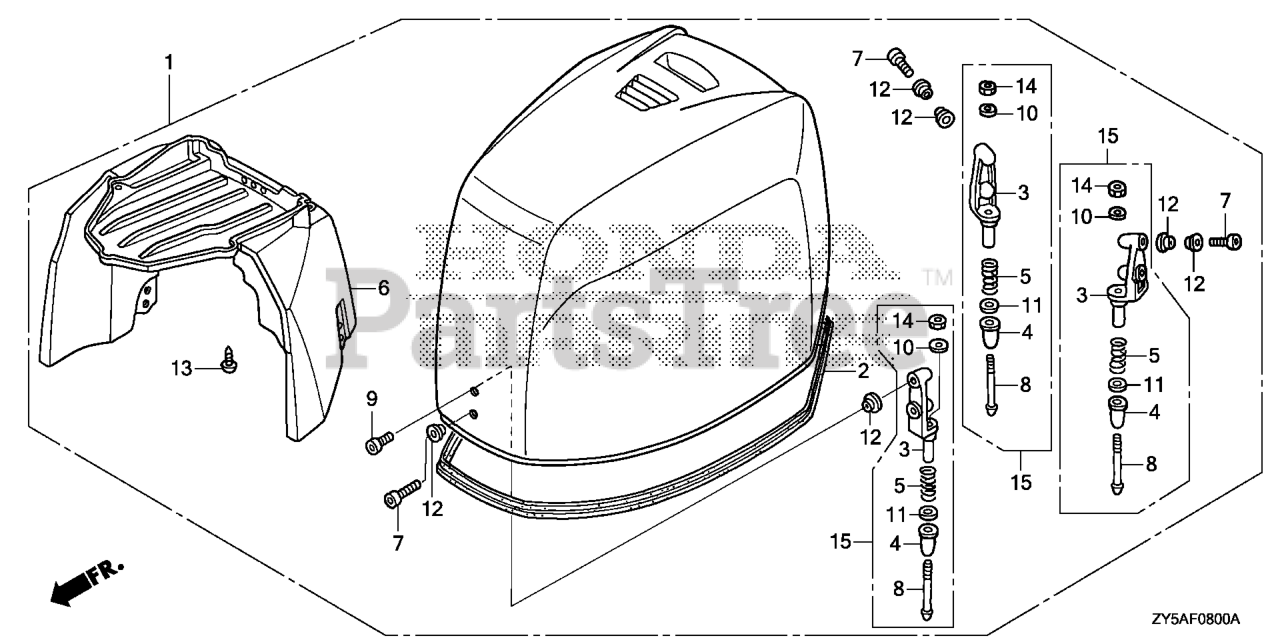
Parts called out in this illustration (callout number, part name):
1	COVER ASSY., ENGINE *NHB14M* (AQUA MARINE SILVER METALLIC)
1	COVER ASSY*NH565*
2	SEAL, ENGINE COVER
3	BRACKET, HOOK
4	DAMPER, HOOK
5	SPRING, LOCK ADJUSTER
6	GUIDE, ENGINE COVER AIR
7	BOLT, SOCKET (6X20)
8	BOLT, COVER LOCK
9	BOLT, SOCKET (6X16)
10	WASHER, PLAIN (6MM) Use from Frame SN 4800713.
11	WASHER, PLAIN (12MM)
12	COLLAR, DISTANCE (6.5X9X3)
13	SCREW, TAPPING (4X12)
14	NUT, HEX. (6MM)
15	HOOK KIT, COVER
